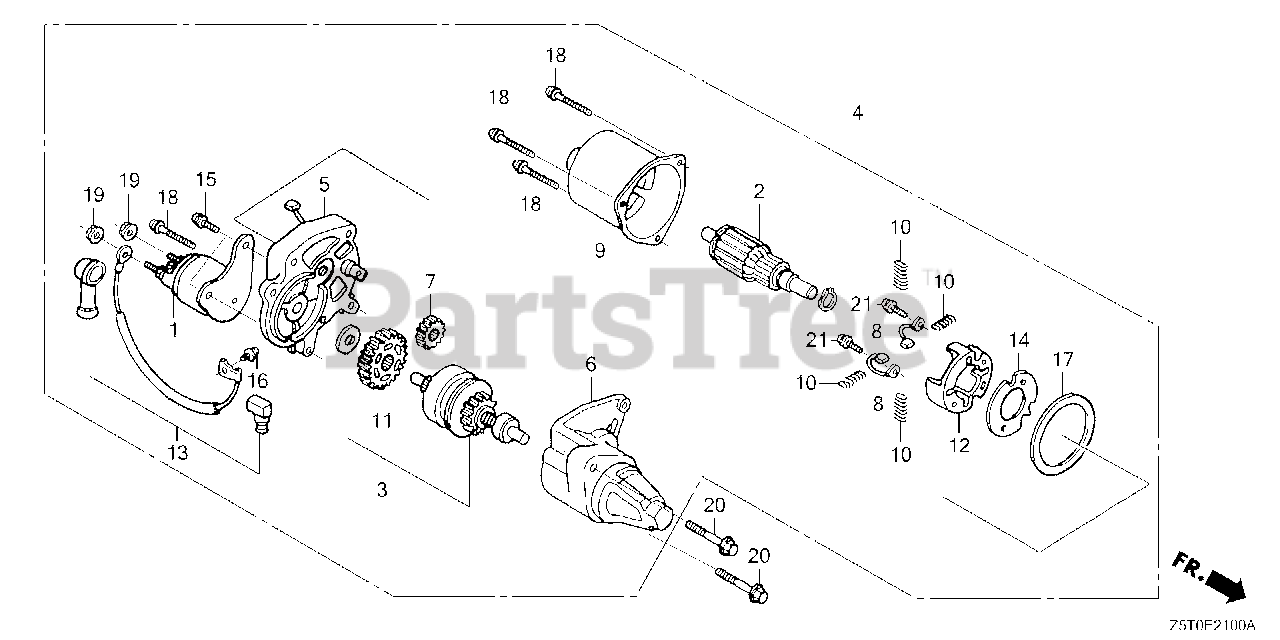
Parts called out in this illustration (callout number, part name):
1	CONTACTOR ASSY.
2	ARMATURE
3	CLUTCH, OVERRUNNING
4	STARTER MOTOR UNIT
5	BRACKET, CENTER
6	BRACKET, FR.
7	GEAR, DRIVE PINION
8	BRUSH
9	YOKE
10	SPRING, BRUSH RETURN
11	GEAR, REDUCTION
12	HOLDER, BRUSH
13	WIRE, WATER COVER
14	INSULATOR
15	BOLT-WASHER (5X14)
16	SCREW-WASHER (4X6)
17	GASKET
18	SCREW-WASHER (5X3)
19	NUT-WASHER (6MM)
20	BOLT, FLANGE (8X35)
21	SCREW-WASHER (4X14)
